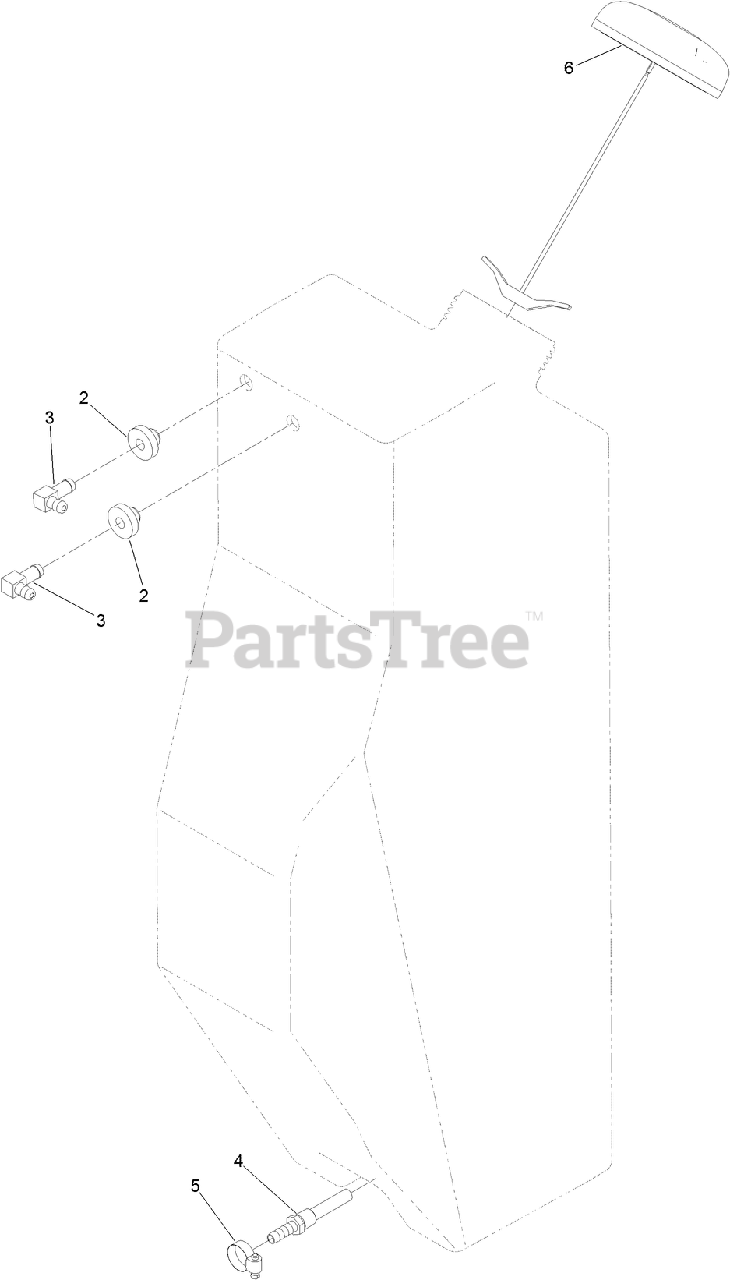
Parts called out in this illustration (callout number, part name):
2	BUSHING
3	FITTING-ELBOW, 90 DEG
4	FITTING-STRAINER
5	CLAMP-HOSE
6	CAP-FUEL
